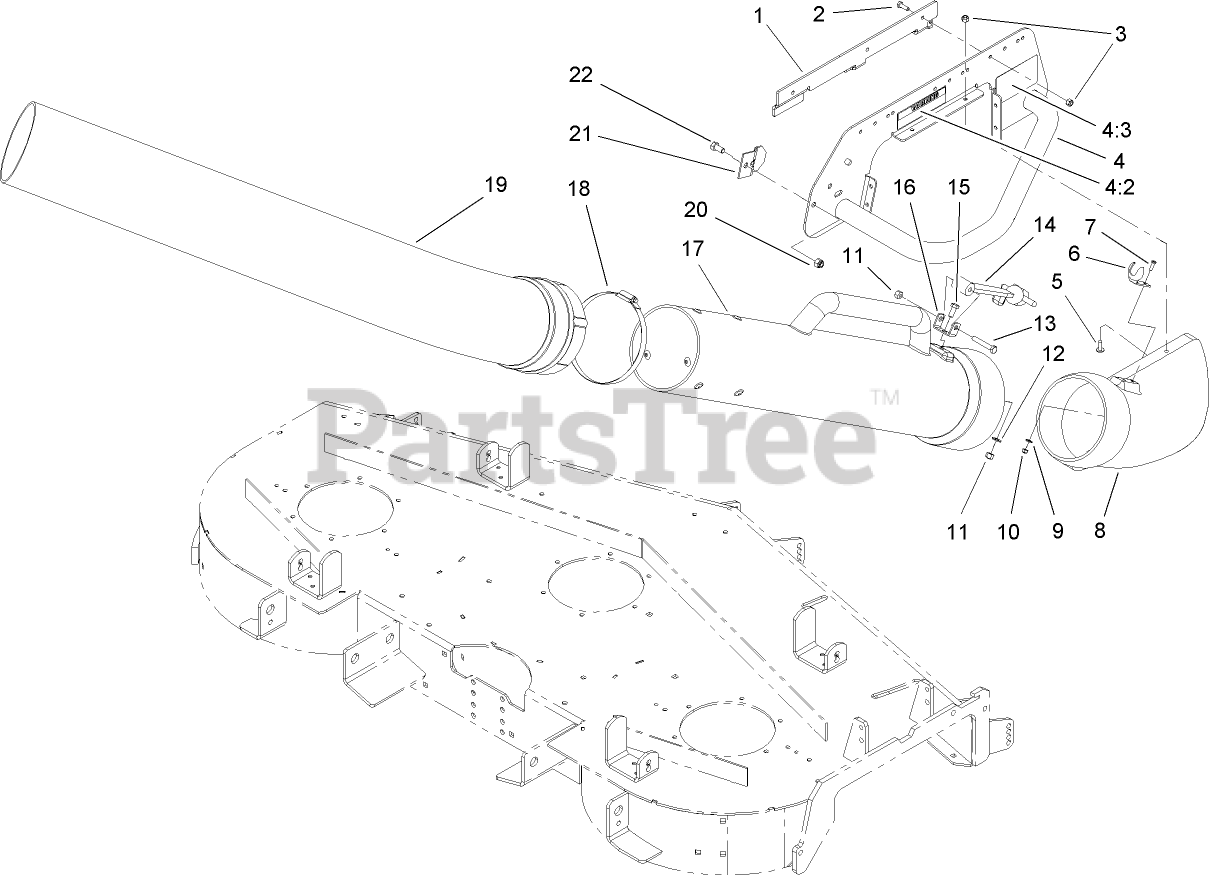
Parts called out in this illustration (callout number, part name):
1	BRACKET-MOUNTING
2	SCREW-HH
3	NUT-LOCK, NI
4	MOUTING PLATE ASM
4:2	DECAL-WARNING
4:3	DECAL-WARNING
5	SCREW-HEAD, TRUSS
6	BRACKET-HOOD
7	SCREW-PPH
9	WASHER-FLAT
10	NUT-LOCK, NI
11	NUT-LOCK, NI
12	WASHER-PLAIN
13	SCREW-HH
14	HOLDDOWN-HOOD
15	SCREW-HH
16	BRACKET-ANCHOR
17	TUBE-STRAIGHT
18	CLAMP-HOSE
19	TUBE-ELBOW
20	NUT-LOCK, NI
21	Bracket-Clamp
22	SCREW-HH
